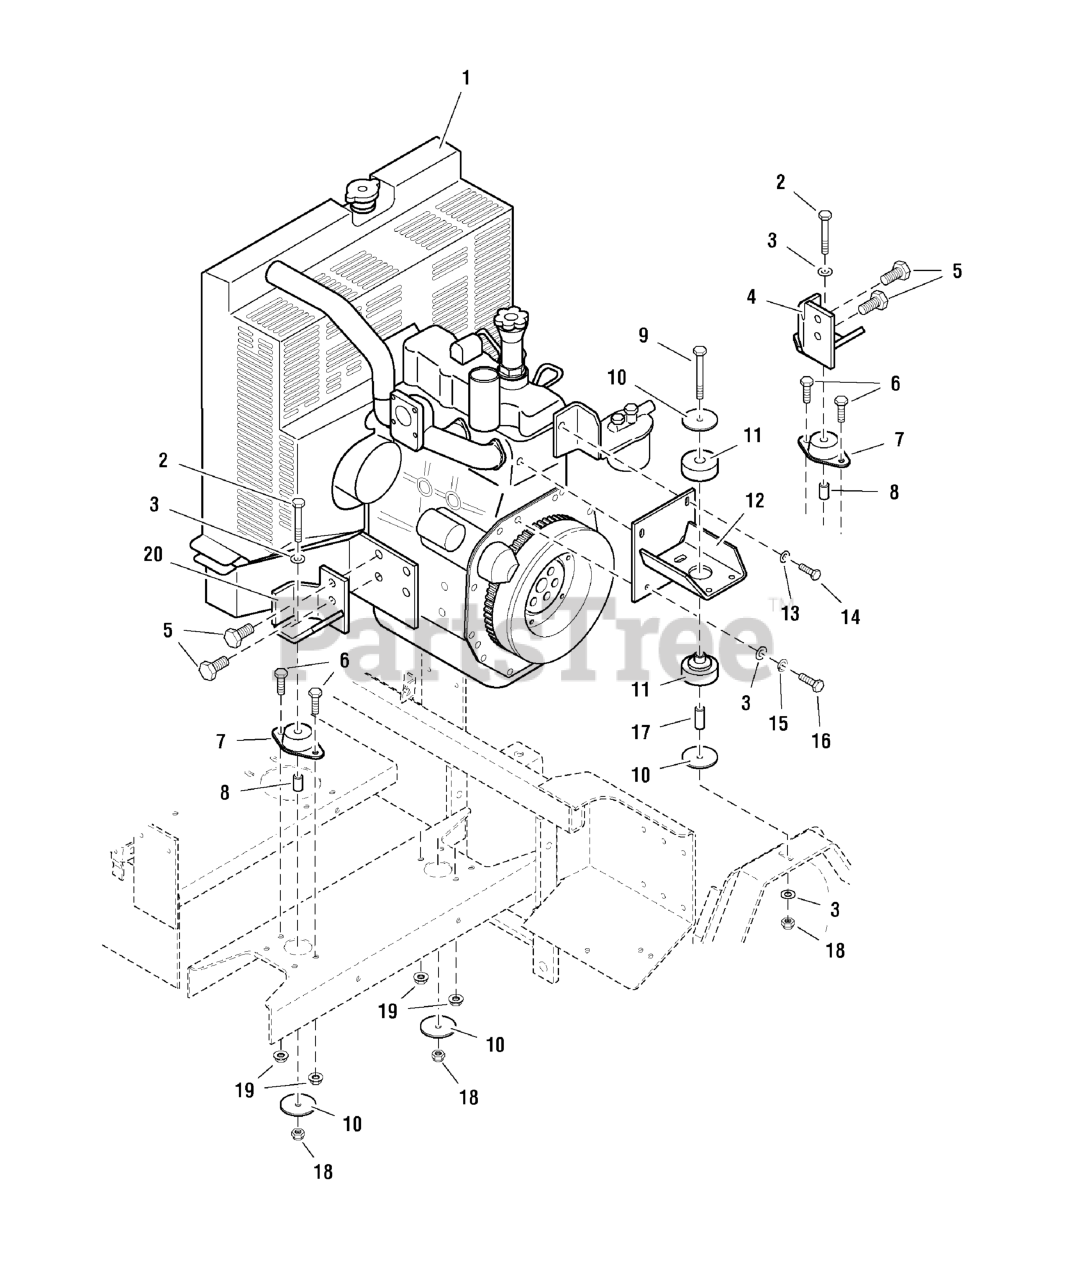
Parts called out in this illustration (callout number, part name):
1	ENGINE, Caterpillar Diesel
2	BOLT, 3/8-16 X 2-1/2" GD5 CZ
3	WASHER, 3/8 SAE
4	MOTOR MOUNT - RH
5	BOLT, M14 x 35MM GD 8.8
6	BOLT, 3/8-16 X 1" GD5 CZ
7	ISO MOUNT, Front
8	SPACER, .38 x .50 x 1.00
9	BOLT, 3/8-16 X 3" GD5 CZ
10	WASHER, 3/8 x 2-1/2
11	ISO MOUNT, Rear (2 piece)
12	MOTOR MOUNT - Upper
13	WASHER, 5/16" SAE
14	BOLT, M8 x 20MM
15	WASHER, 3/8" Lock
16	BOLT, M10 x 30MM
17	SPACER, .38 x .62 x 1.62
18	NUT, 3/8-16 HEX NYLON LOCK
19	NUT, 3/8-16 Hex Serrated Flange
20	MOTOR MOUNT - LH
